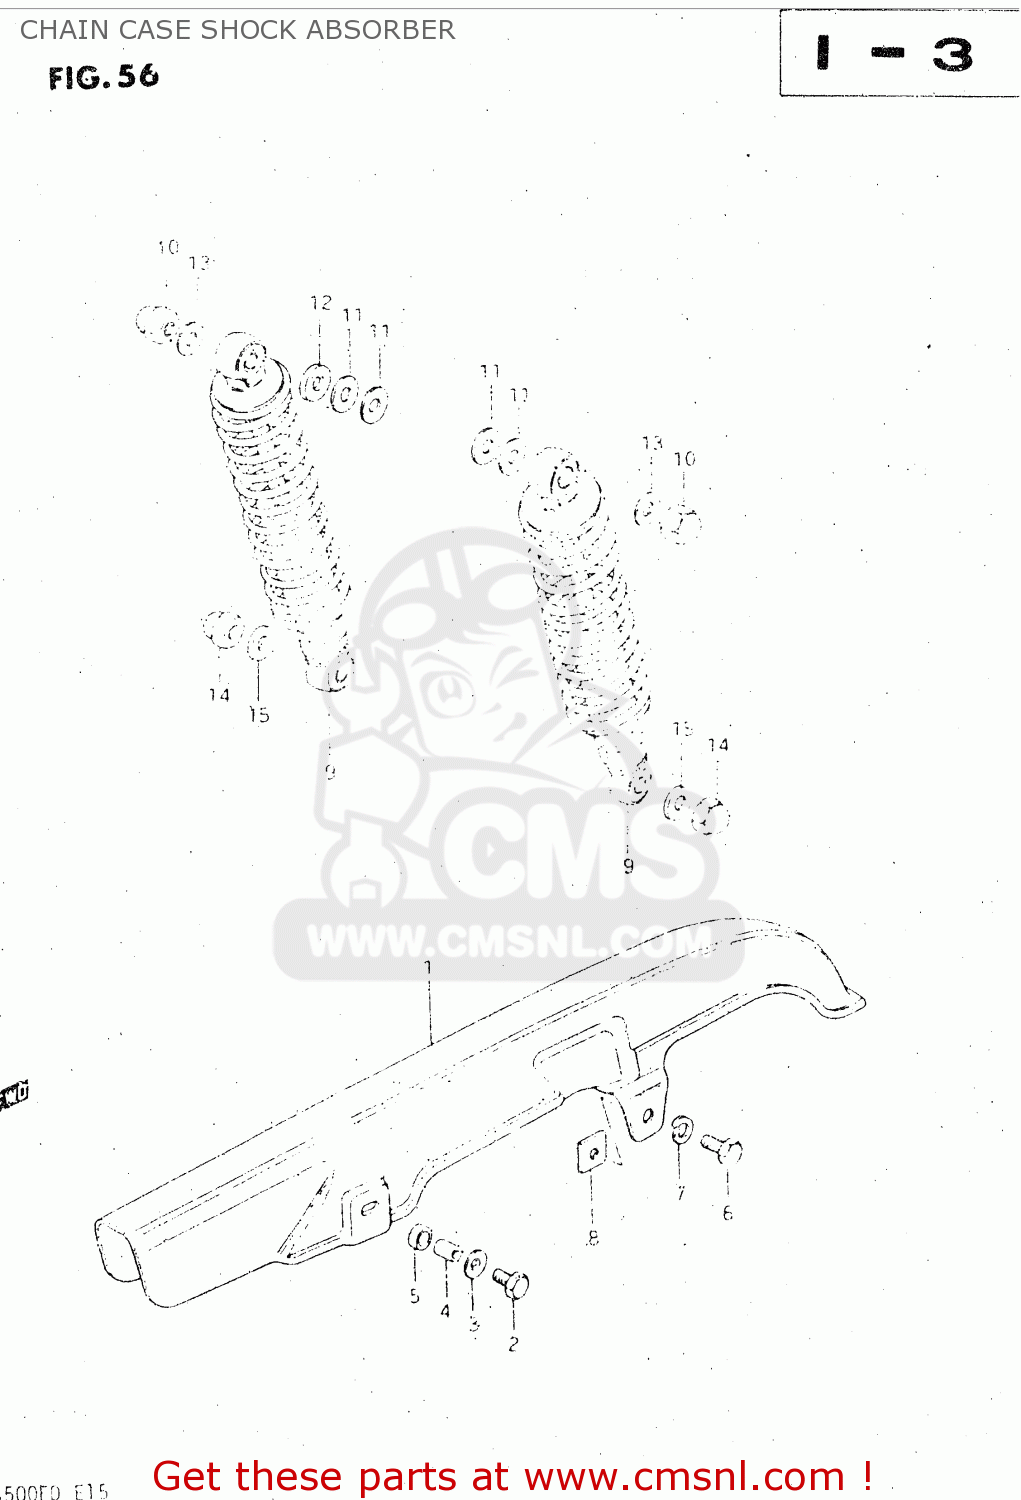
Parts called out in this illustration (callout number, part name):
1	CASE,CHAIN
2	BOLT
3	WASHER(6.5X18X1)
4	SPACER (6.1X8X5.2)
5	CUSHION
6	BOLT, UPPER
7	LOCK WASHER
8	NUT,CHAIN CASE RR
9	SHOCK ABSORBER, REAR
10	NUT
11	WASHER
12	WASHER (12.5X24X3.2)
13	WASHER
14	NUT, LOWER LH
15	WASHER
